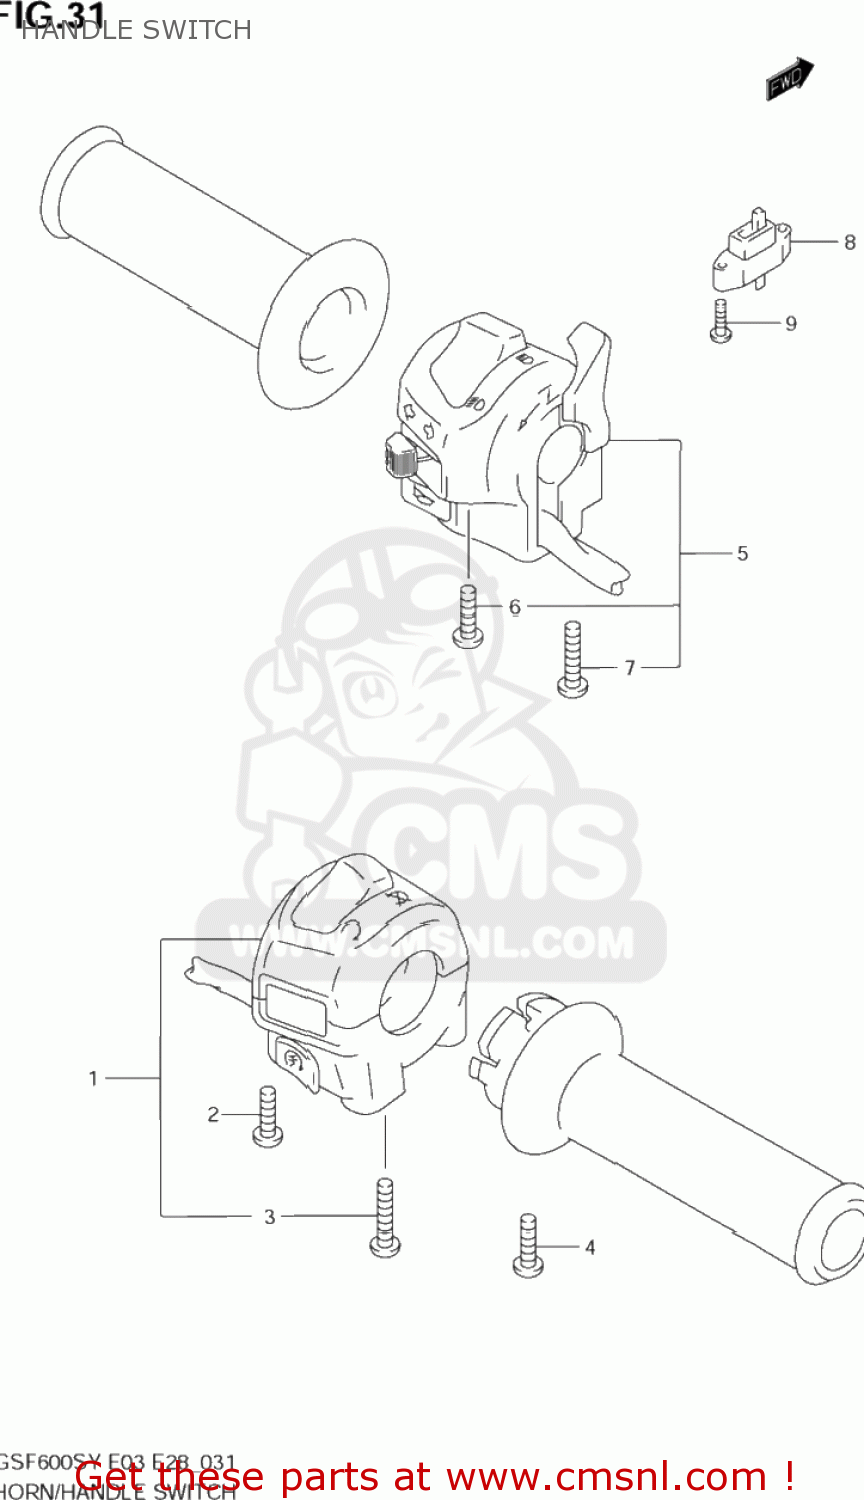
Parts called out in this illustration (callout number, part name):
1	SWITCH ASSY,HANDLE,R
2	SCREW
3	SCREW
4	SCREW
5	SWITCH ASSY,HANDLE,L
6	SCREW
7	SCREW
8	SWITCH ASSY,CLUTCH
9	SCREW
